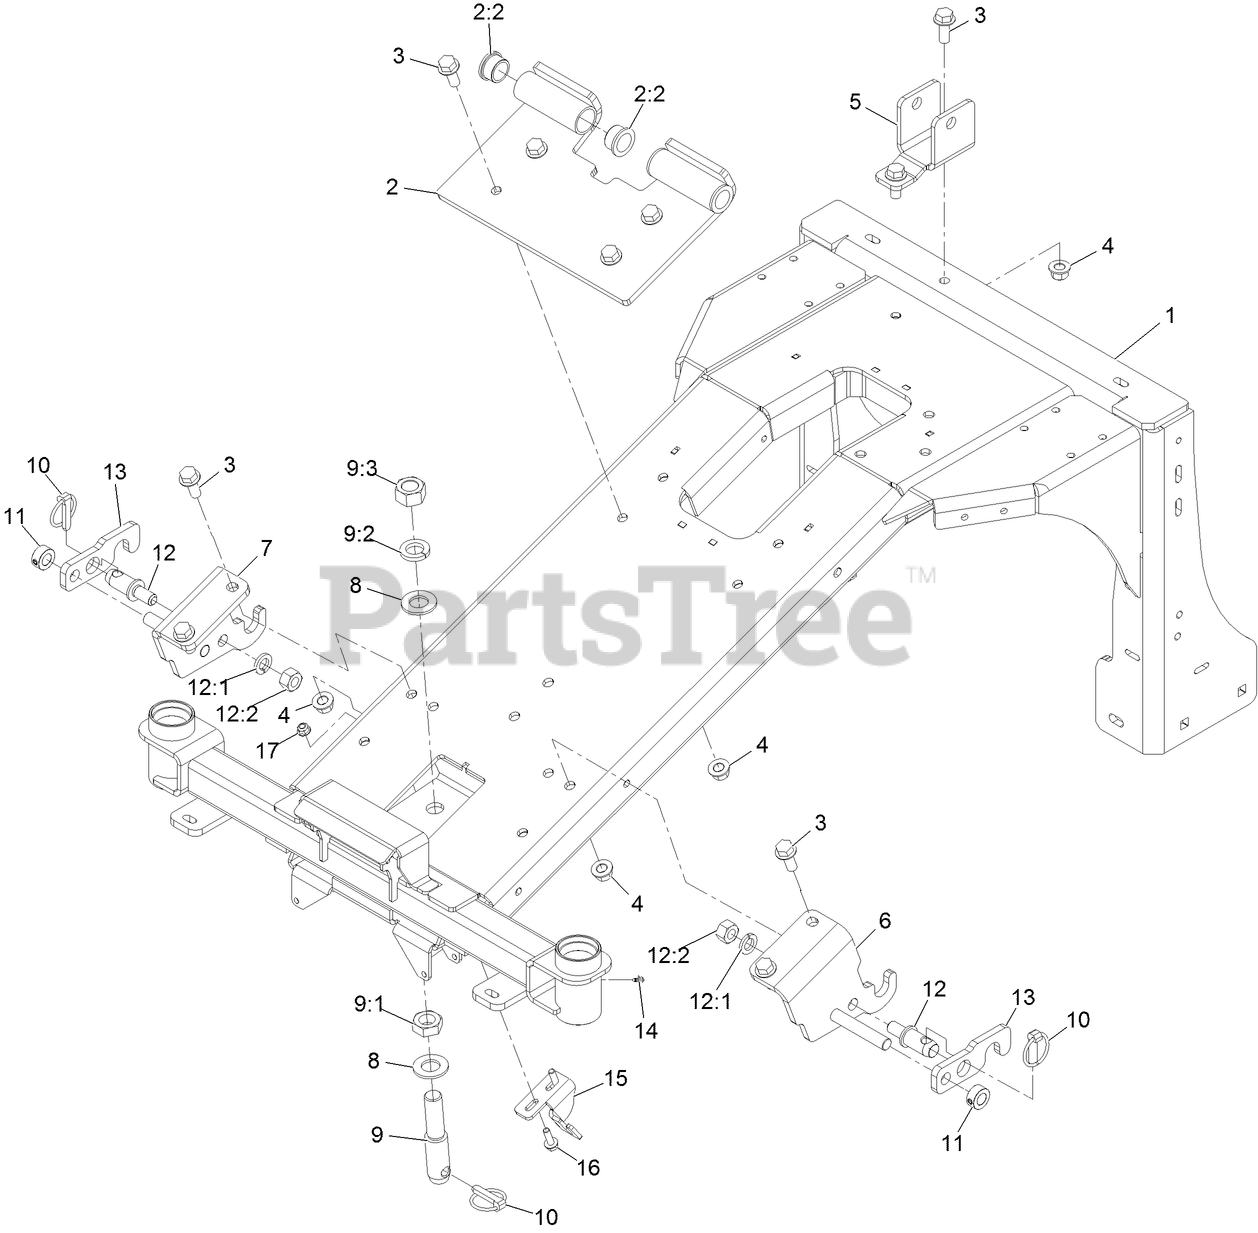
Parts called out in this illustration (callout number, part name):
1	FRONT FRAME ASM
2	PIVOT-ARM, LIFT ASM
2:2	BUSHING-FLANGE
3	SCREW-HHF
4	Nut-Lock 1/2-13
5	BRACKET-MOUNT, CYLINDER
6	X-REF 135-9471-05
7	HITCH PIN-RH
8	WASHER-FLAT
9	1-1/8 X 5-1/4 LIFT ARM PI
9:1	NUT-JAM
9:2	WASHER-LOCK/SP
9:3	NUT-HEX
10	PIN-LYNCH
11	5/8 SHAFT COLLAR
12	7/8 X 3-1/8 ANCHOR PIN (2
12:1	WASHER-LOCK
12:2	NUT-HEX
13	PLATE-ATTACHMENT, LOCK
14	FITTING-GREASE, ZERK
15	BRACKET-CABLE, LCS
16	SCREW-HH
17	NUT-HF, NI
